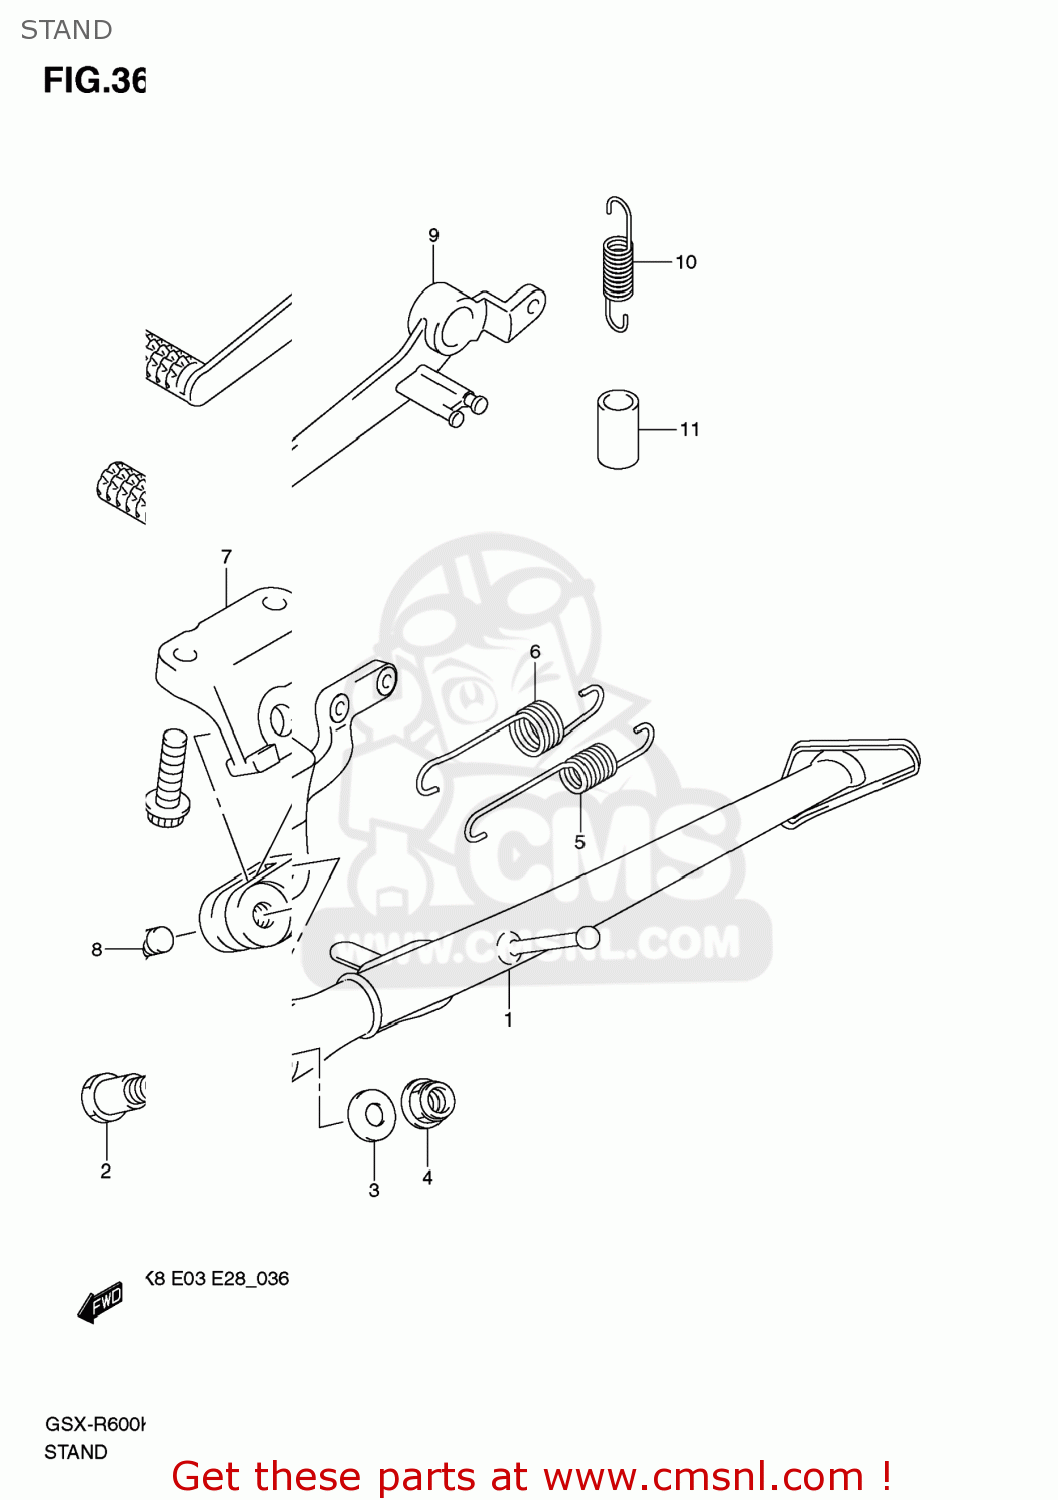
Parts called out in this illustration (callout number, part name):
1	STAND,PROP
2	BOLT(10X37.5)
3	SEAT,VALVE SPRING EXH OUTER
4	NUT
5	SPRING
6	SPRING
7	BRACKET,PROP STAND
8	BOLT(10X28)
9	PEDAL,BRAKE
10	SPRING
11	HOSE(11X15X600)
